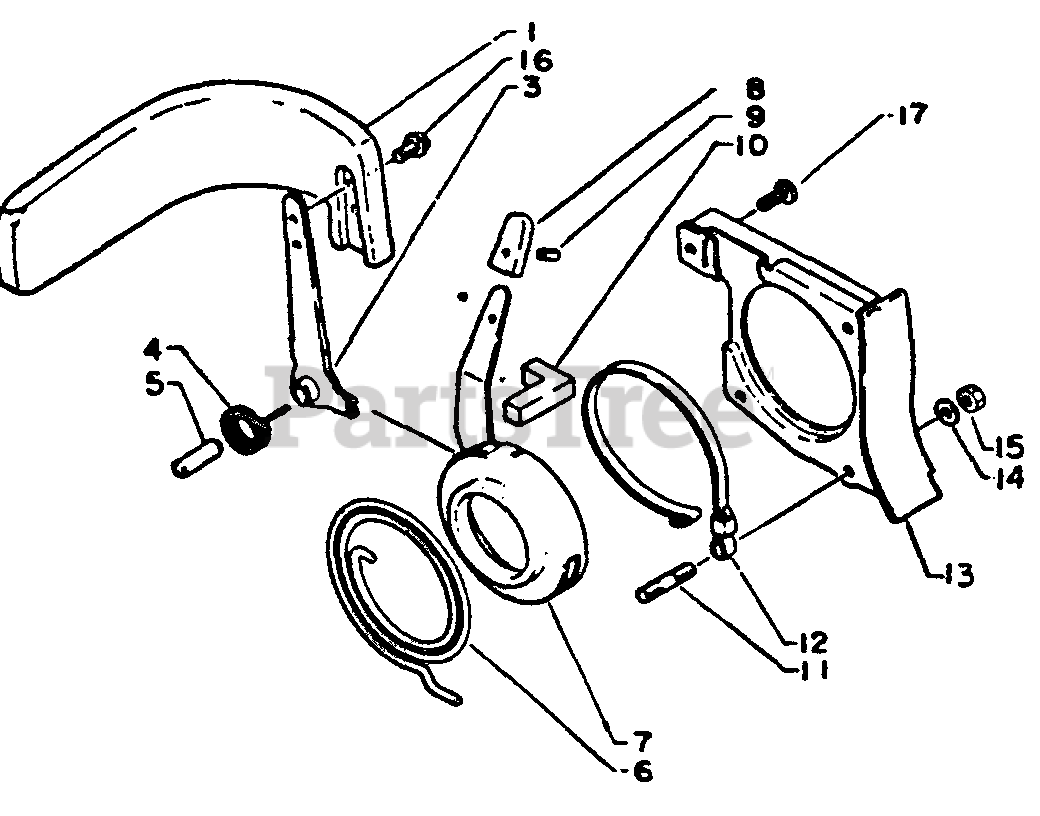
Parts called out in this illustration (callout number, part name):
1	LEVER, BRAKE
3	LEVER, BRAKE
4	SPRING, RETURN
6	SPRING, BRAKE
7	CASE, BRAKE BAND
8	RESET, BRAKE
9	PIN - SPRING -- 3X8
10	SEAL, DUST
11	STUD
12	BAND, BRAKE
16	SCREW - 4X12
17	SCREW - 4X10
